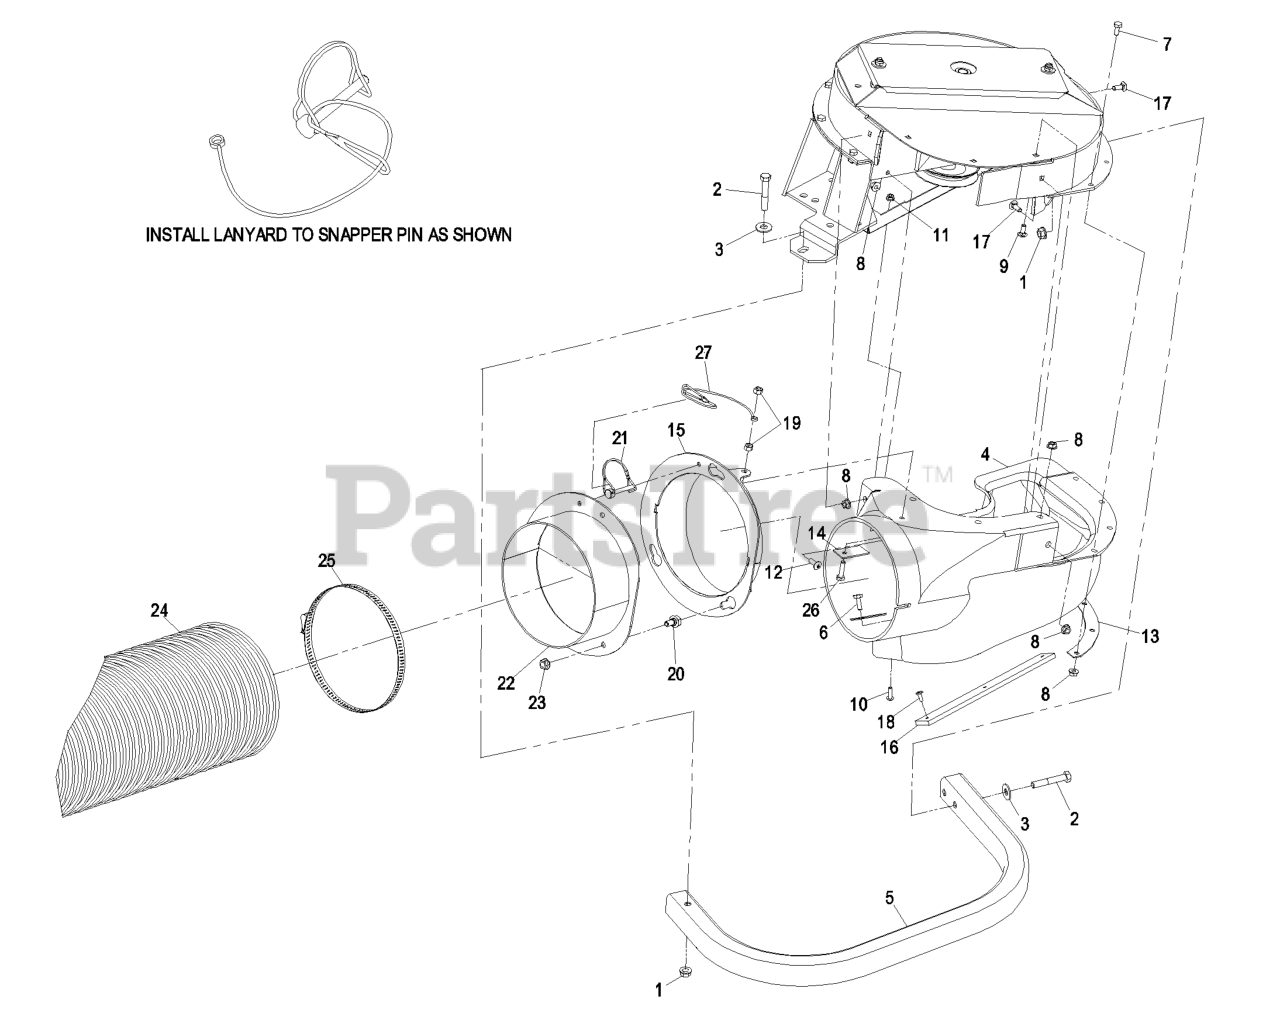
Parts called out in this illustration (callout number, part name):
1	NUT-HHF, WHIZ
2	SCREW-HH
3	WASHER-FLAT
4	ASM,BLOWER CHUTE
6	SCREW-HH
7	SCREW-HH
9	SCREW-CARR
10	SCREW-HEAD, TRUSS
13	PLATE-BACKING, BLOWER
14	PLATE-BACKING
16	PLATE,REINFORCEMENT LARGE
17	BOLT-CARR
18	RIVET-BLIND
19	NUT-LOCK, NI
20	BOLT-SHOULDER,HFH
21	PIN-HITCH
22	WLD,FRUVD HOSE ADAPTER
24	HOSE,FRUVD
26	SCREW-HH
27	LANYARD-NYLON
